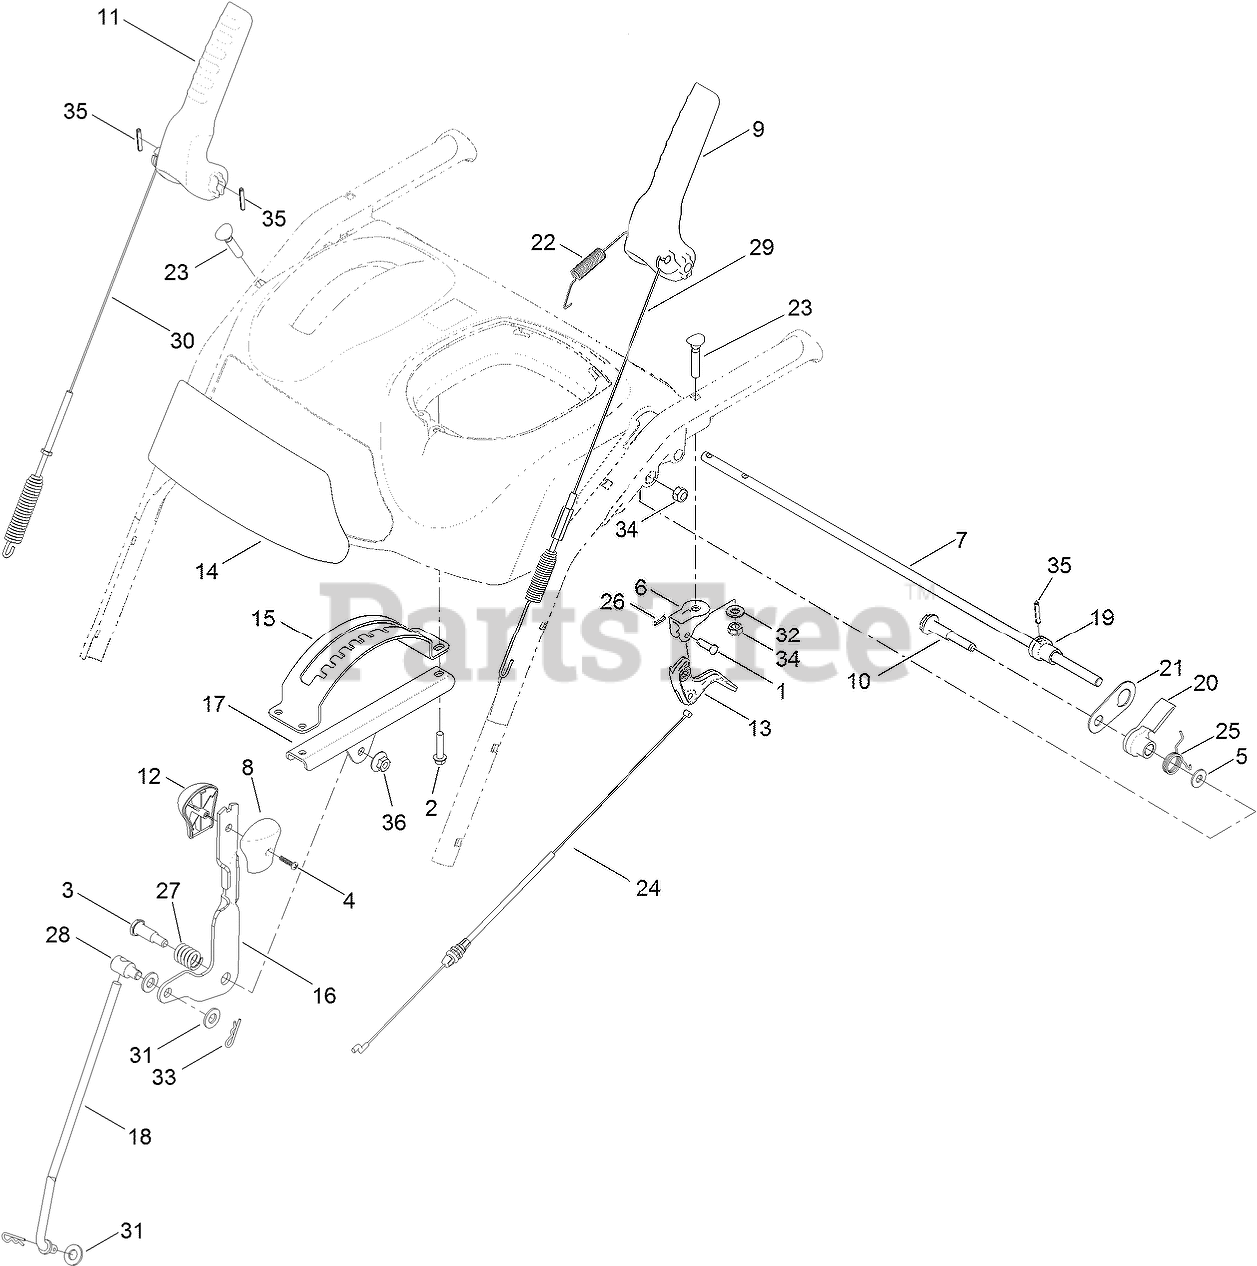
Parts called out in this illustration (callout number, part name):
1	PIN-CLEVIS
2	SCREW-PLASTITE
3	SCREW-SHOULDER
4	SCREW-PPH
5	WASHER-FLAT
6	MOUNT-CLUTCH, LEVER
7	ROD-LOCKOUT
8	KNOB-SHIFT, LH
9	LEVER-TRACTION
10	SCREW-SHOULDER
11	LEVER-AUGER
12	KNOB-SHIFT, RH
13	LEVER-CLUTCH
14	DECAL-CONTROL PANEL
15	GUIDE-SELECTOR, SPEED
16	SELECTOR-SPEED
17	BRACKET-SELECTOR, SPEED
18	ROD-SHIFT
19	CAM-LOCKOUT
20	LATCH-LOCKOUT
21	LINK-LOCKOUT
22	SPRING-TENSION
23	SCREW-HANDLE
24	CABLE-CLUTCH
25	SPRING-TORSION
26	PIN-HAIR
27	SPRING-COMPRESSION
28	TRUNNION-ROD
29	CABLE-TRACTION
30	CABLE-AUGER
31	WASHER-FLAT
32	WASHER-FLAT
33	PIN-COTTER
34	NUT-LOCK, NI
35	PIN-SPRING
36	NUT-HF
